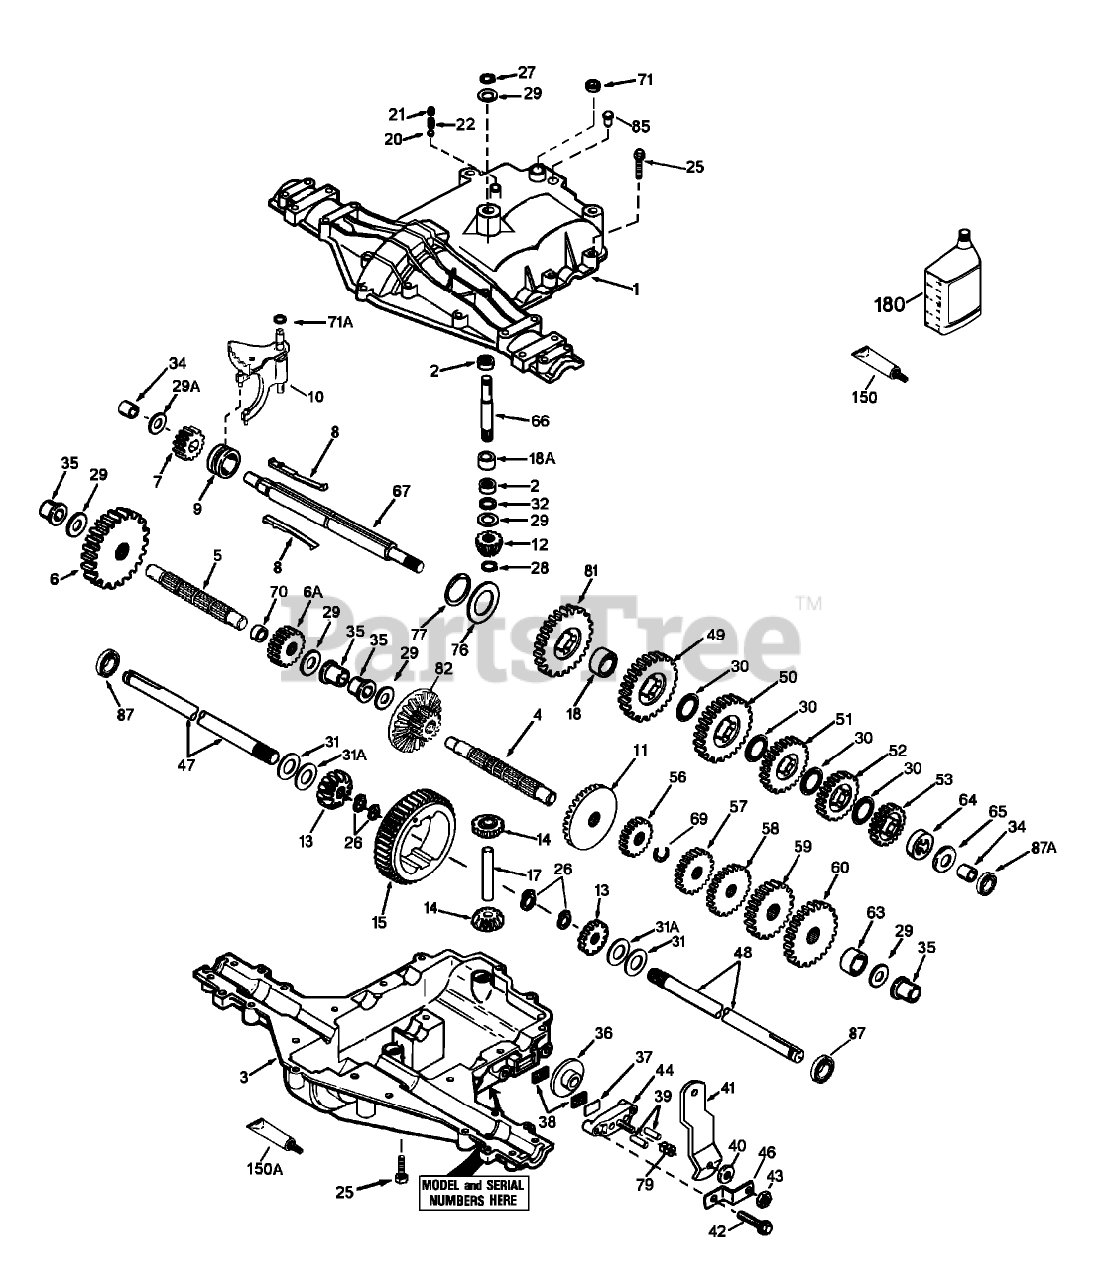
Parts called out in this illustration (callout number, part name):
1	Transaxle Cover
2	Bearing-Needle
3	Transaxle Case
4	Countershaft
5	Output Shaft
6	Spur Gear (38 teeth)
6A	Spur Gear (15 teeth-steel)
7	Spur Gear (11 teeth-steel)
8	Shift Key
9	Shift Collar
10	Shift Rod Fork
11	Bevel Gear (30 teeth)
12	Input Bevel Pinion (13 teeth)
13	Bevel Gear (16 teeth-steel)(Incl. 13)
14	Bevel Gear (16 teeth-steel)(Incl. 13)
15	Ring Gear (43 teeth)
17	Drive Pin
18	Spacer
18A	Spacer
20	Ball-Steel
21	Screw-Set
22	Spring
25	Ring Set (.020 O S)
26	Retaining Ring (pkg of 2)
27	Ring-Snap
28	Ring-Retainer
29	Washer
29A	Washer
30	Washer
31	Washer
31A	Flat Washer (.062 wide)
32	Oil Seal
34	Bushing
35	Flanged Bushing
36	Brake Disk
37	Brake Pad Plate
38	Pad-Brake 2/Pkg
39	Dowel Pin
40	Washer
41	Brake Lever
42	Ring Set (.020 O S)
43	Locknut
44	Nozzle-Carburetor
46	Bracket
47	Axle (11-15/16" long)
48	Axle (16-1/2" long)
49	Spur Gear (29 teeth-steel)
50	Spur Gear (23 teeth-steel)
51	Spur Gear (20 teeth)
52	Spur Gear (16 teeth-steel)
53	Spur Gear (15 teeth-steel)
56	Spur Gear (11 teeth-steel)
57	Spur Gear (17 teeth-steel)
58	Spur Gear (20 teeth)
59	Spur Gear (24 teeth-steel)
60	Spur Gear (25 teeth)
63	Spacer
64	Spacer
65	Washer
66	Input Shaft
67	Shifter Brake Shaft
69	Retaining Ring
70	Spacer
71	Cut Seal-Square
71A	O Ring
76	Washer
77	Inverted Retaining Ring
79	Piston ASM (.020 O S)
81	Spur Gear (27 Teeth)
82	Bevel Spur Gear (30 13 teeth)
85	Pipe Plug
87	Oil Seal
87A	Oil Seal
150	Liquid Gasket RTV Silicone
150A	Liquid Gasket Loctite #242
180	Gear Oil
